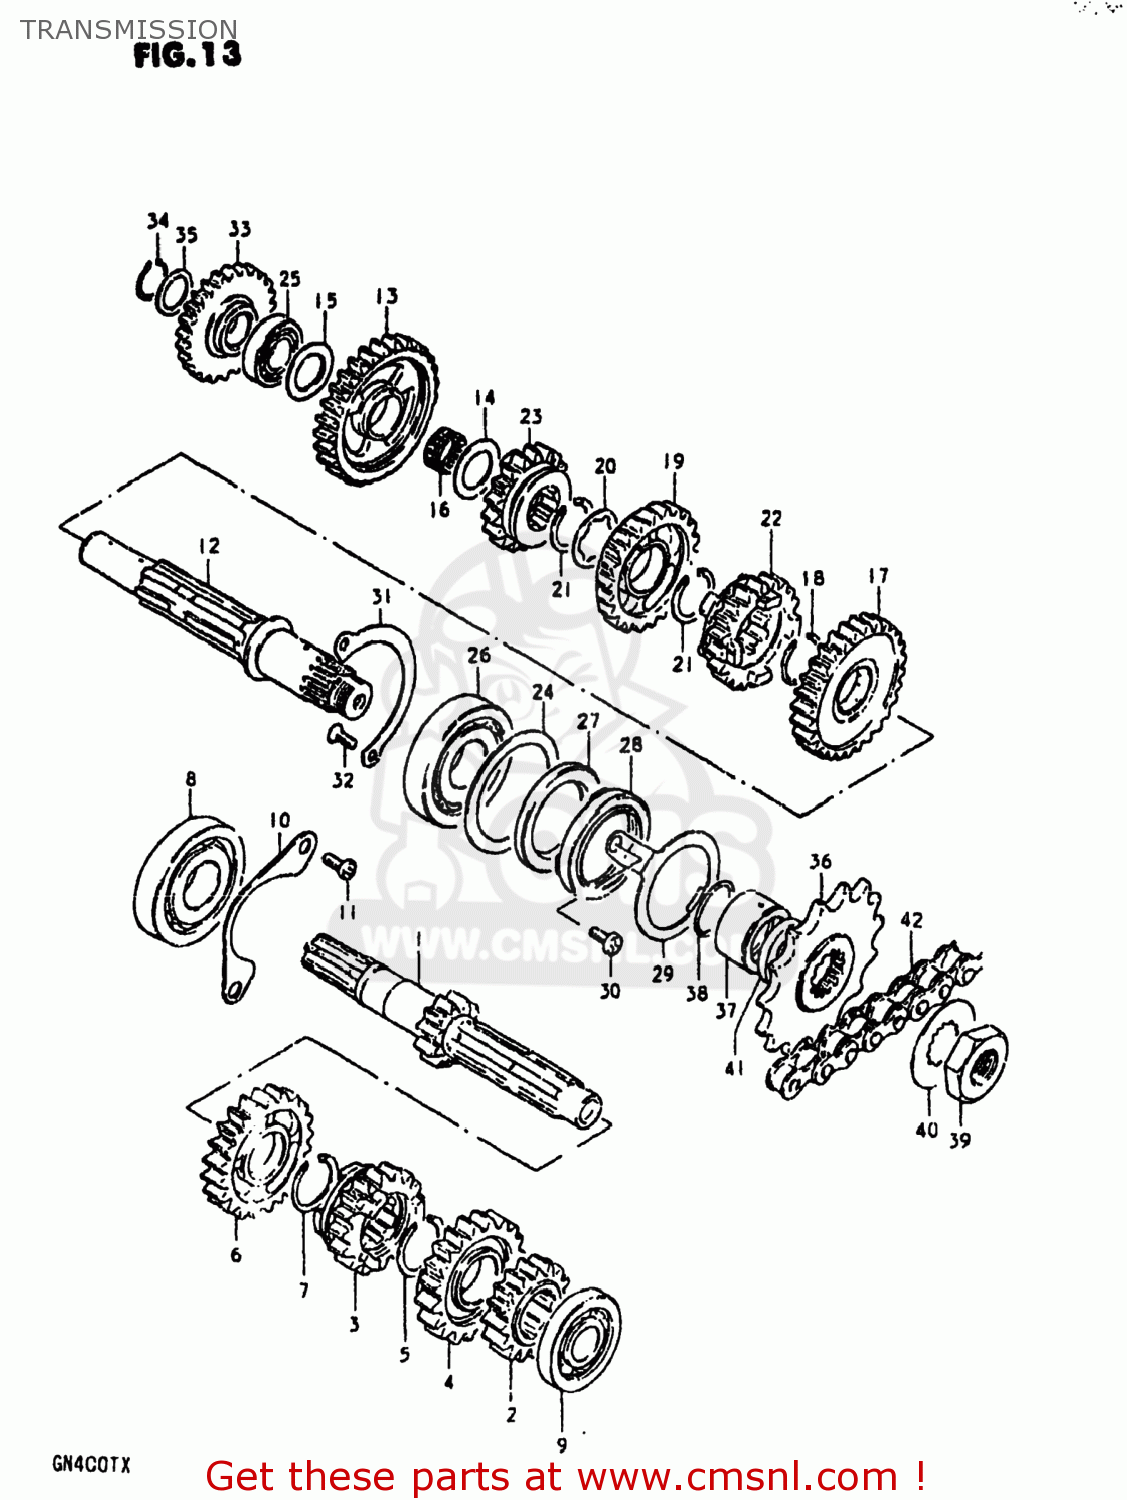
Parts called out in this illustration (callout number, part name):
1	SHAFT,COUNTER
2	GEAR,SECOND DRIVE
3	GEAR,THIRD DRIVE
4	GEAR,FOURTH DRIVE
5	CIRCLIP
6	GEAR,FIFTH DRIVE
7	CIRCLIP
8	BEARING
9	BEARING
10	PLATE,COUNTERSHAFT BEARING
11	SCREW 6X12
12	SHAFT,DRIVE
13	GEAR,FIRST DRIVEN
14	WASHER
15	WASHER
16	BEARING(17X21X9.8)
17	GEAR,SECOND DRIVEN
18	CIRCLIP
19	GEAR,THIRD DRIVEN
20	WASHER,LOCK
21	CIRCLIP
22	GEAR,FOURTH DRIVEN
23	GEAR,FIFTH DRIVEN
24	WASHER
25	BEARING(17X36X12)
26	BEARING(22X56X16)
27	OIL SEAL (30X47X5)
28	SEAL,OIL(30X47X7)
29	PLATE,DRIVESHAFT OIL
30	SCREW 6X12
31	RETAINER,DRIVE SHAFT BEARING
32	SCREW
33	GEAR,KICK STARTER IDLER(NT:25)
34	CIRCLIP
35	WASHER
36	SPROCKET,ENGINE(NT:16)
37	SPACER,ENGINE SPROCKET
38	O RING(D:2.5,ID:21)
39	NUT
40	WASHER,LOCK
41	SPACER
42	CHAIN ASSEMBLY,DRIVE
